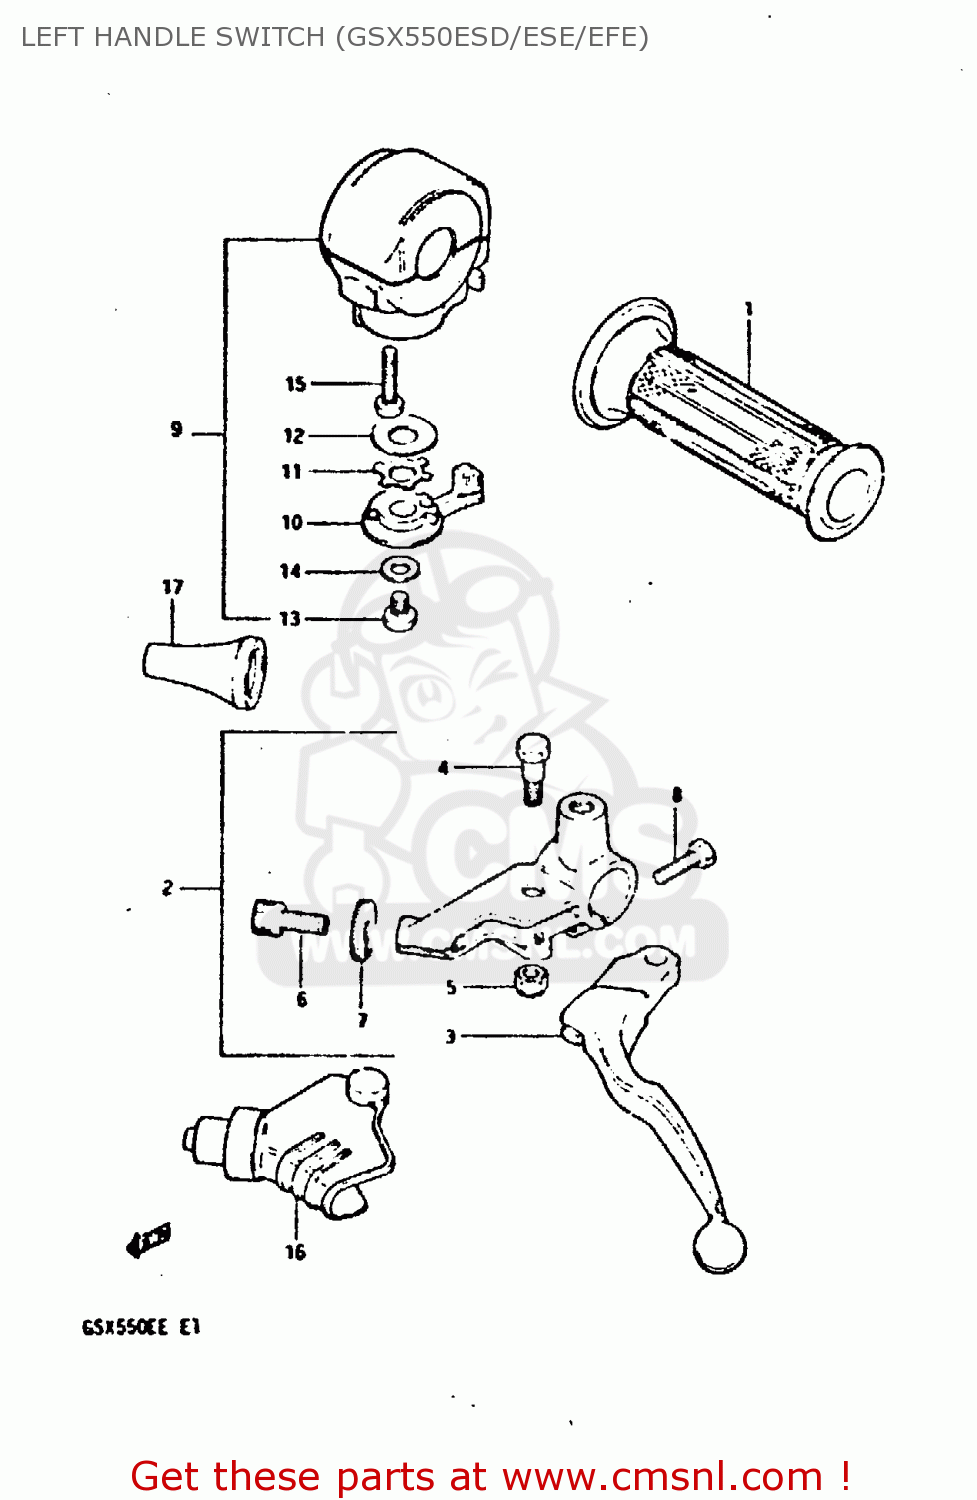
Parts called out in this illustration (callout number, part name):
1	GRIP,L
2	LEVER ASSY,CLU
3	LEVER,CLUTCH
4	BOLT,LEVER PIVOT
5	NUT 6MM
6	ADJUSTER,CABLE
7	NUT,CABLE ADJUSTER
8	BOLT,CLUTCH LEVER HOLDER
9	SWITCH ASSY,HA
10	LEVER,STARTER
11	WASHER
12	WASHER
13	SCREW
14	WASHER
15	SCREW
16	COVER,CLUTCH LEVER
17	BOOT,CLUTCH CABLE
